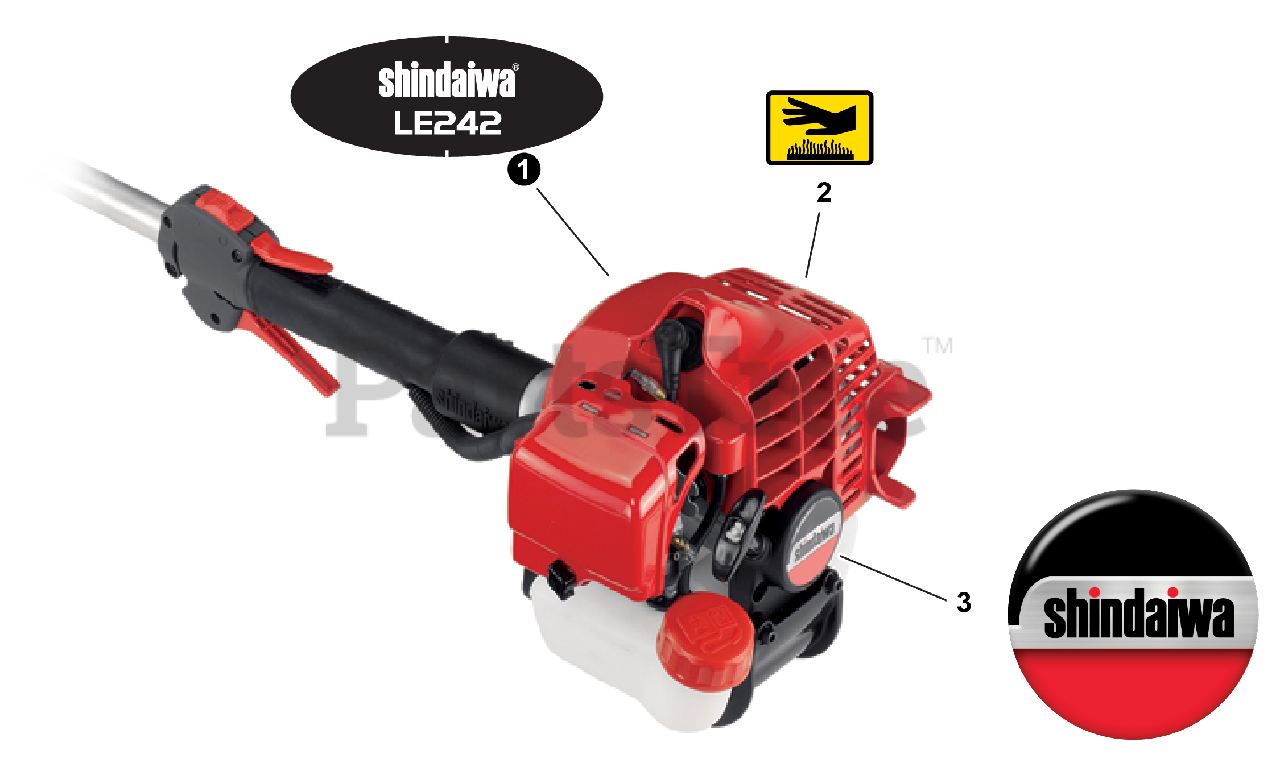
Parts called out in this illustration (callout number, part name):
1	LABEL, MODEL - LE242
2	LABEL, CAUTION - HOT
3	LABEL, RECOIL STARTER
